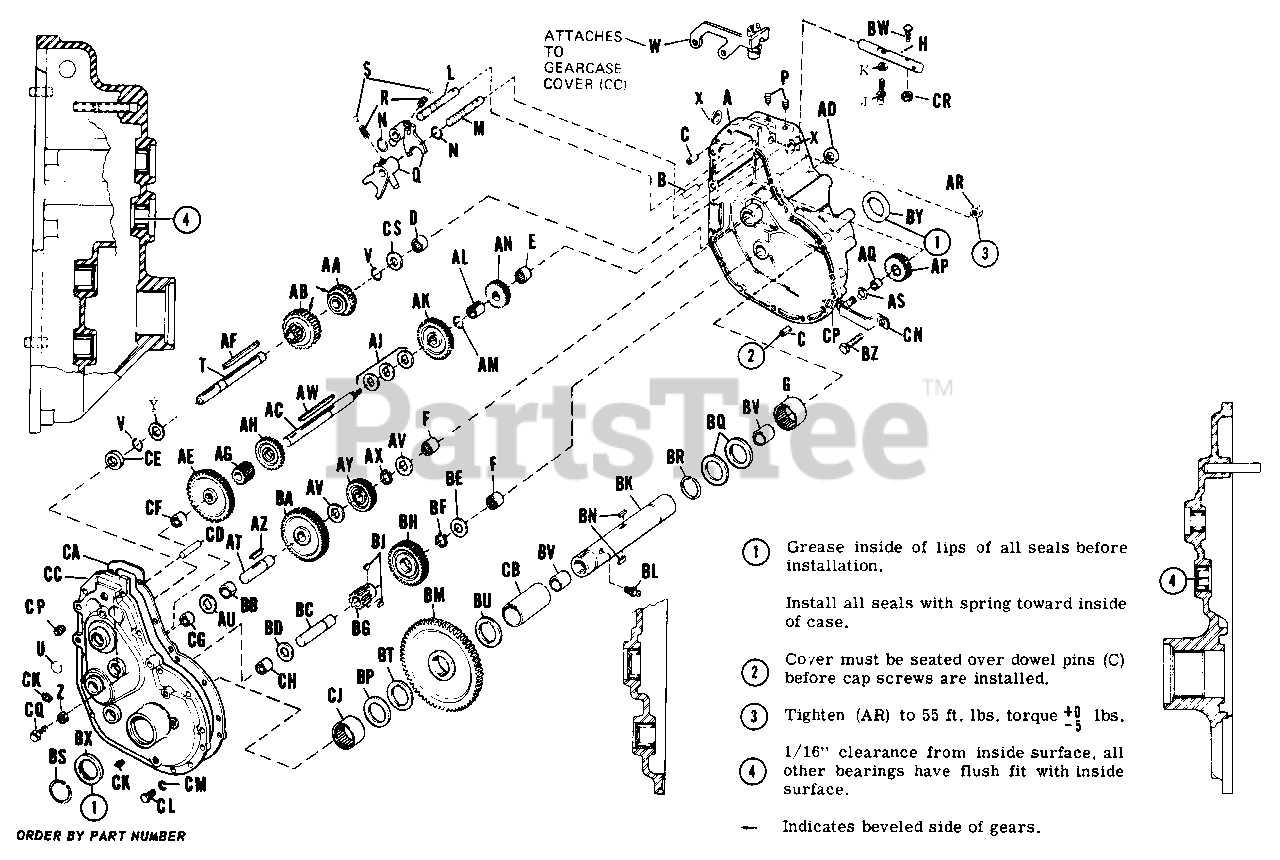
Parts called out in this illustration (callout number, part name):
A	Case, Gear, Complete w/bearings and dowel pins (Includes "B" thru "G")
D	Needle Bearing
E	Needle Bearing
F	Needle Bearing
G	Needle Bearing
H	Shift Rod
J	Shift Stem
K	Full Hex. Nut, 3/8"-24 N.F.
L	Shifter Shaft Rev., Med.
M	Shifter Shaft High, Low
N	Retaining Ring
P	Set Screw, Hollow Head, Cone Point, 5/16"-18 x 1/2"
S	Shift Lock Ball
T	Pulley Shaft
V	Retaining Ring
W	Switch Support
Y	Retaining Ring
Z	Hex. Nut Jam. 5/16"-18
AA	Pinion Assembly Rev. II
AB	Pinion Assembly, I and III
AC	Shaft, 1st Intm.
AE	Driven I, Gear
AG	Pinion, 1st Intm.
AH	Pinion. Driven, III
AJ	Trans. Gear Spacer
AK	Driven II Gear
AM	Retaining Ring
AN	Reverse Pinion
AP	Reverse Gear
AQ	Rev. Gear Spacer
AR	Lock Nut. 1/2"-20 N.F.
AT	Shaft, 2nd. Intm.
AX	Retaining Ring
AY	Pinion, 2nd. Intm.
BA	Gear, 2nd. Intm.
BC	Shaft, 3rd. Intm.
BF	Retaining Ring
BG	Pinion, 3rd, Intm.
BH	Gear, 3rd, Intm.
BJ	Key Woodruff
BK	Axle Tube w/bushing
BL	Grease Fitting
BM	Drive Gear
BT	Axle Tube Washer
BU	Axle Tube Washer
BW	Carriage Belt 5/16"-18 x 1
BZ	Hex. Cap Screw, 3/8"-16 x 1-1/4"
CA	Gear Case Gasket
CB	Axle Tube Spacer
CC	Gear Case Cover, Complete w/bearings
CE	Ball Bearing
CF	Needle Bearing
CG	Needle Bearing
CH	Needle Bearing
CJ	Needle Bearing
CK	Pipe Plug, 3/8"
CL	Hex. Cap Screw, 5/16"-18 x 1"
CM	Lock Washer, 5/16"
CN	Rev. Gear Pin Assembly
CP	Pipe Plug, 3/8"
CQ	Hex. Cap Screw, 5/16"-18 x 1-1/4"
CR	Hex Jam Nut 5/16"-18
